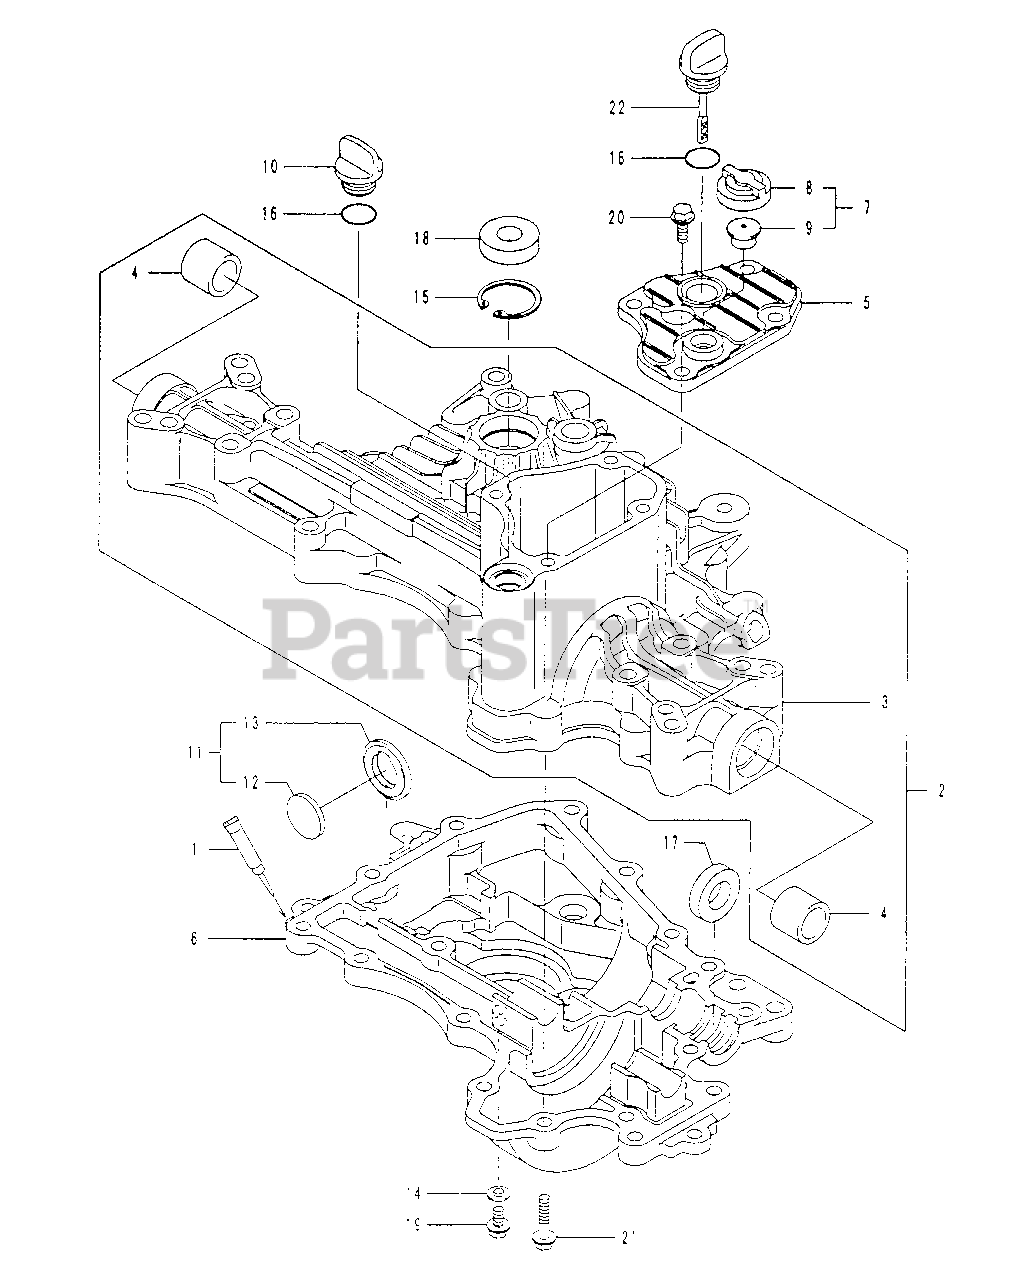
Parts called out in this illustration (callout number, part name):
1	SEALANT
2	UPPER CASE CMP.
3	UPPER CASE
4	BUSHING 19.05
7	VENT VALVE 15
8	CAP,VENT VALVE
9	BODY, VENT VALVE
10	CAP, OIL 20
11	MAGNET CMP.
12	MAGNET 28 X 3.5
13	COVER MAGNET
14	WASHER, SEAL 8
16	PACKING P 18
17	SEAL TC123207
18	SEAL TC153507
19	BOLT 8 X 12
20	BOLT 8 X 20
21	TAPPING, SCREW 8 X 30
22	CAP 20 X 49
